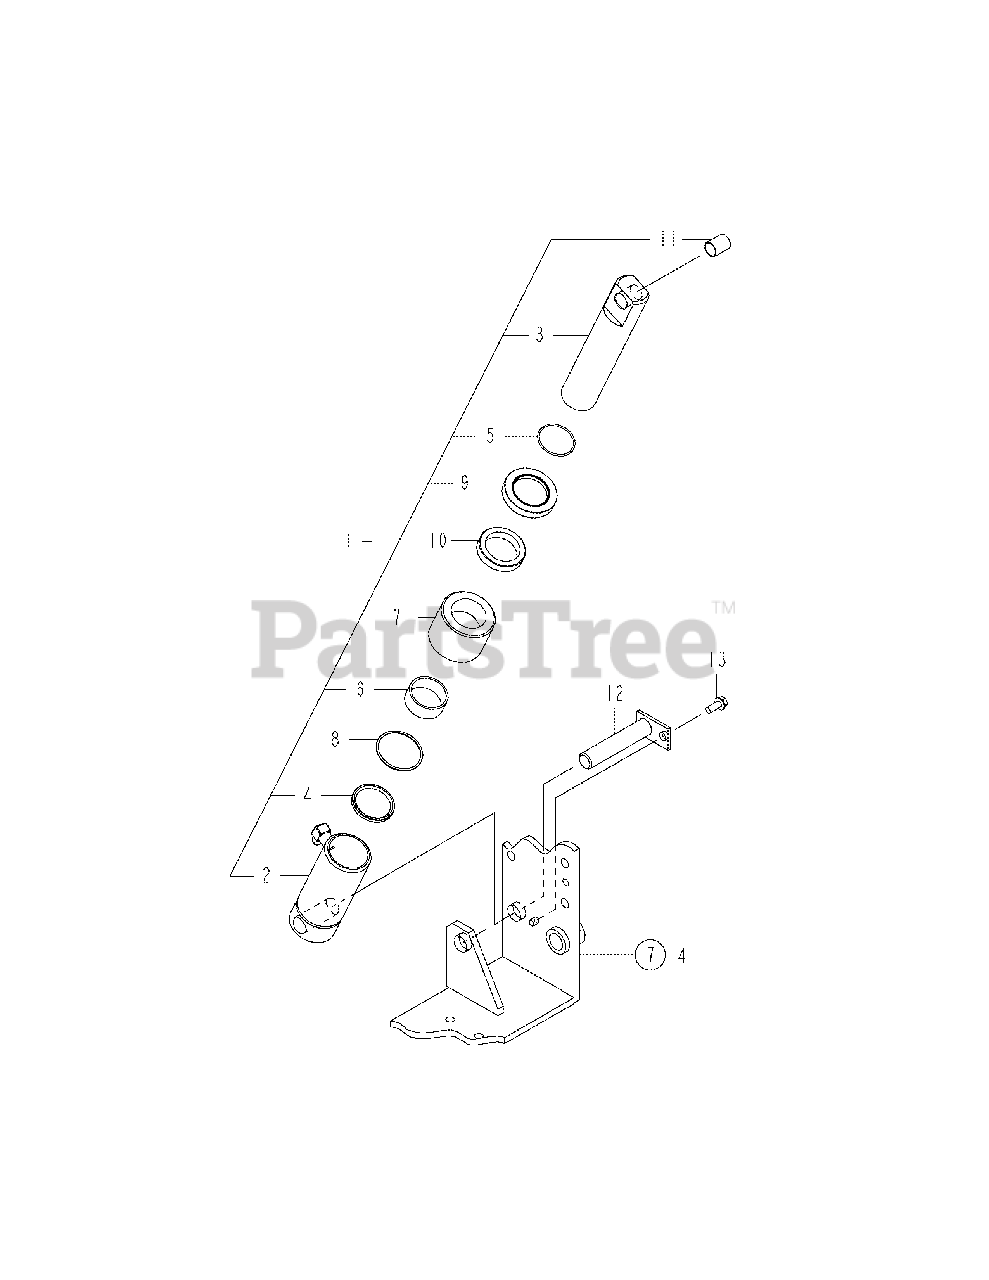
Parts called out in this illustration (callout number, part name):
1	Cylinder Assy, Hyd.
11	Bearing, 18 X 25
12	Pin Cmp (Cylinder
13	Bolt M10X 25 Plated
